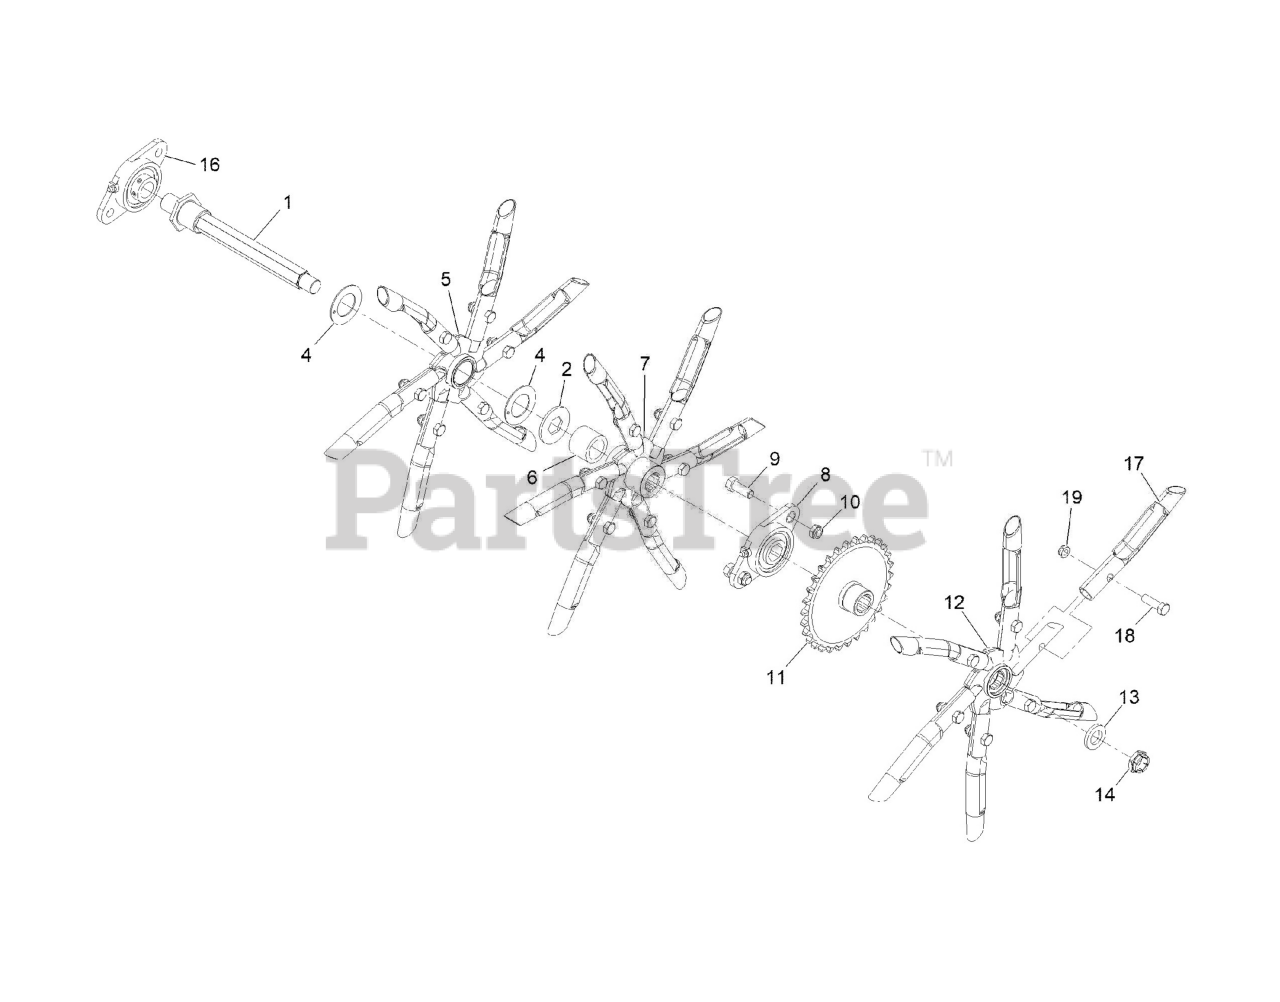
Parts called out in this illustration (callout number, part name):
1	TINE SHAFT ASM
2	KEEPER-TINE, FLOATING
4	WASHER-THRUST
5	FLOATING SPYDER ASM
6	SPACER-TINE
7	DRIVEN SPYDER ASM
8	BEARING-HEX BORE
9	SCREW-HH
10	NUT-LOCK
11	SPROCKET ASM
12	DRIVEN SPYDER ASM
13	WASHER-SPACER
14	NUT-LOCK
16	BEARING-ROUND BORE
17	TINE-CORING (3/4 INCH)
18	SCREW-HH
